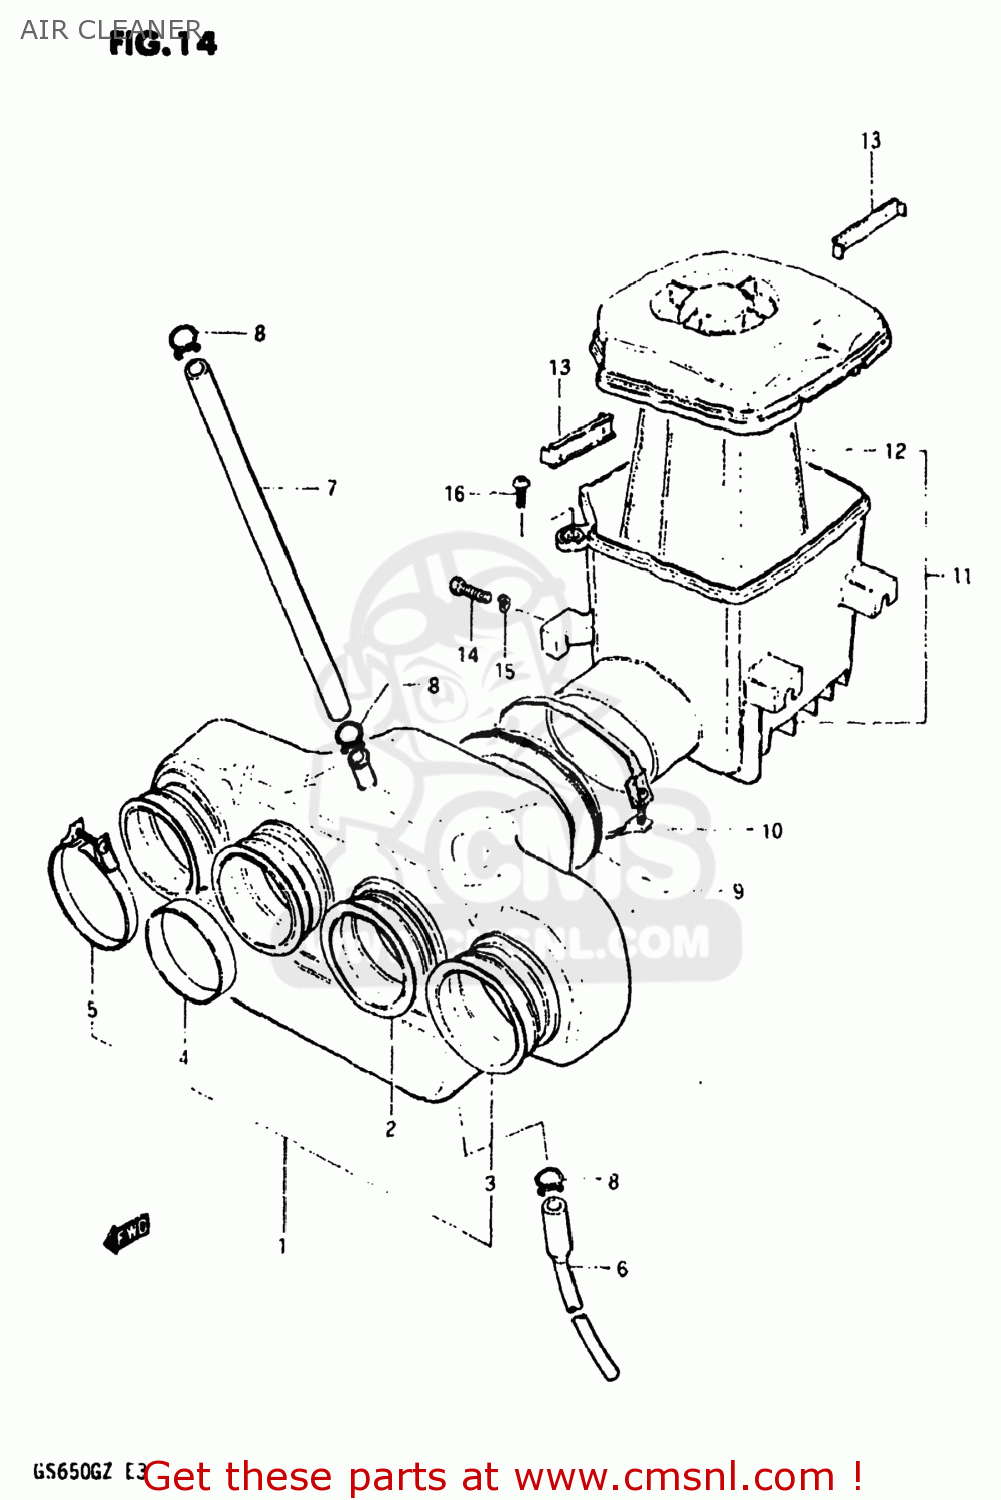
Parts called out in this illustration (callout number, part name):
1	CASE,AIR CLEANER,FRONT
2	TUBE,OUTLET,INNER
3	TUBE,OUTLET OUTER
4	RING,CARBURETOR AIR IN
5	CLAMP
6	DRAIN TUBE
7	HOSE
8	CLIP
9	JOINT,HOSE AIR CLEANER
10	CLAMP
11	CLEANER SET,AIR,REAR
12	FILTER ASSY
13	SLIDER
14	BOLT, UPPER
15	LOCK WASHER
16	SCREW
